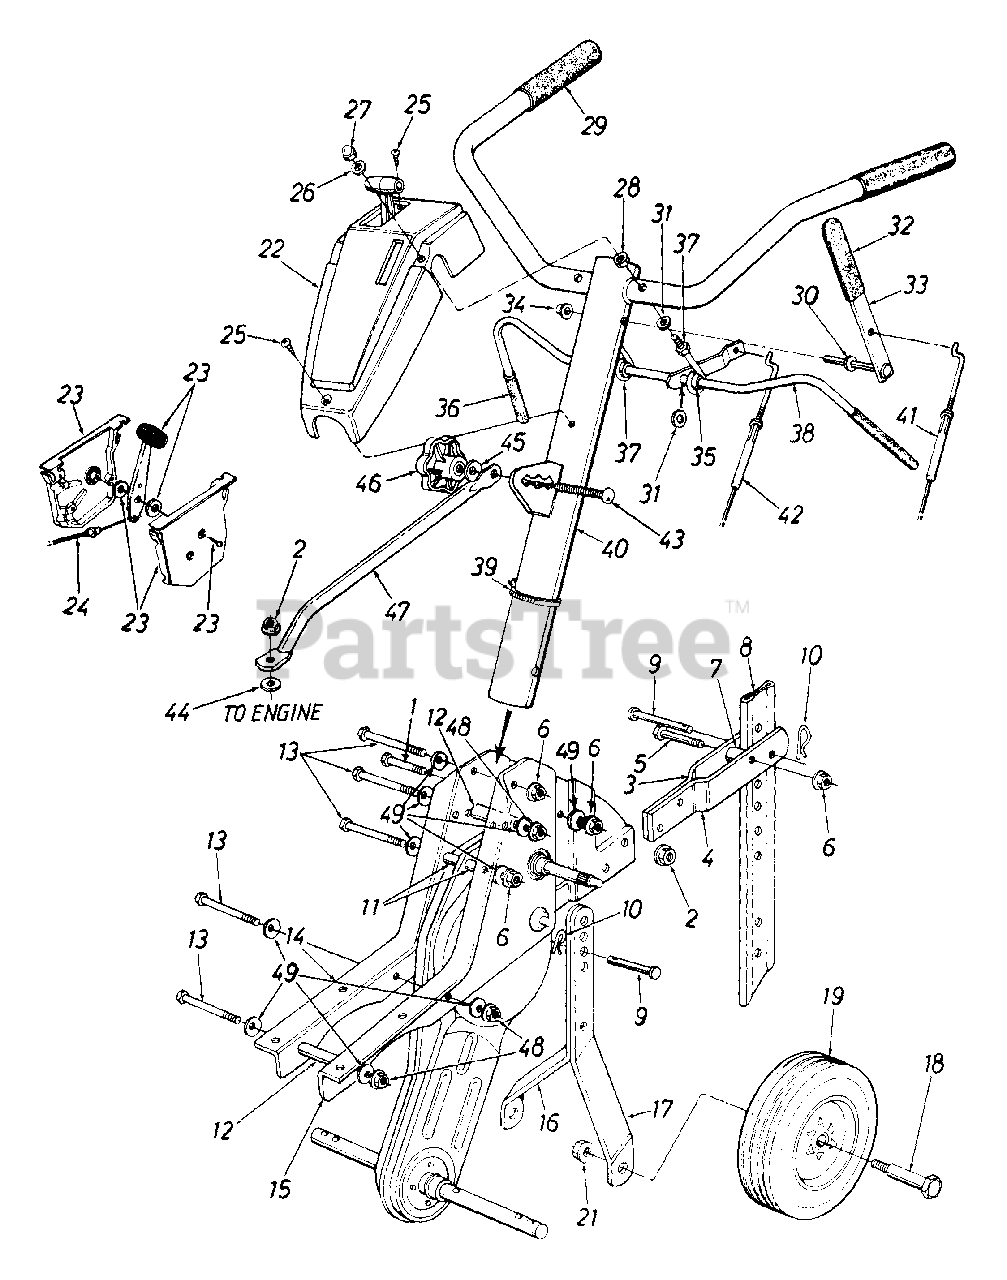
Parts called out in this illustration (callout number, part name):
1	Hex Bolt 5/16-18 x 1.25" Lg.
2	Hex Flange L-Nut 5/16-18 Thd. (Gr. 5)
5	Hex Bolt 5/16-18 x 1.5" Lg.
6	Hex Flange L-Nut 5/16-18 Thd. (Gr. 5)
7	Spacer .32" I.D. x .75" 0 D.
9	Clevis Pin .375" I.D. x 1.75" Lg.
10	Internal Cotter Pin
11	Spacer .326" I.D. x .47" 0 D.
12	Spacer .322" I.D. x .44" I.D.
13	Hex Bolt 5/16-18 x 2.75" Lg.
17	Wheel Hanger Brkt.-L.H.
18	Shld. Bolt .498" Dia. x 1.45" Lg.
19	Wheel Ass'y. 8" x 1.75"
23	Throttle Control Box Ass'y.
24	Throttle Control Wire 35" Lg.
25	Truss Mach. AB-Tap Scr. #10 x .5" Lg.
26	Fl-Wash 266" I.D. x 625" O.D
27	Hex L-Stop Nut 1/4-28 Thd
28	Hex Nut 1/4-28 Thd
29	Grip - Handle
30	Fl-Wash..344" I. D. x 62" O. D.
31	Fl-Wash..385" I. D. x .62" O . D.
32	Grip - Reverse Lever
33	Reverse Handle Ass'y
34	Cap Speed Nut
35	Plastic Bushing 38" I. D.
36	Grip - Clutch
37	Clutch Handle Eye Bolt
42	Clutch Control Cable - Forward
43	Carr. Bolt 5/16-18 x 1" Lg.
44	Fl-Wash .344" 1.D x 1.12" O.D.
45	Bell-Wash. 345" I.D. x .88" O.D.
46	Hand Knob
49	Bell-Wash 345" I D. x .88" O.D.
